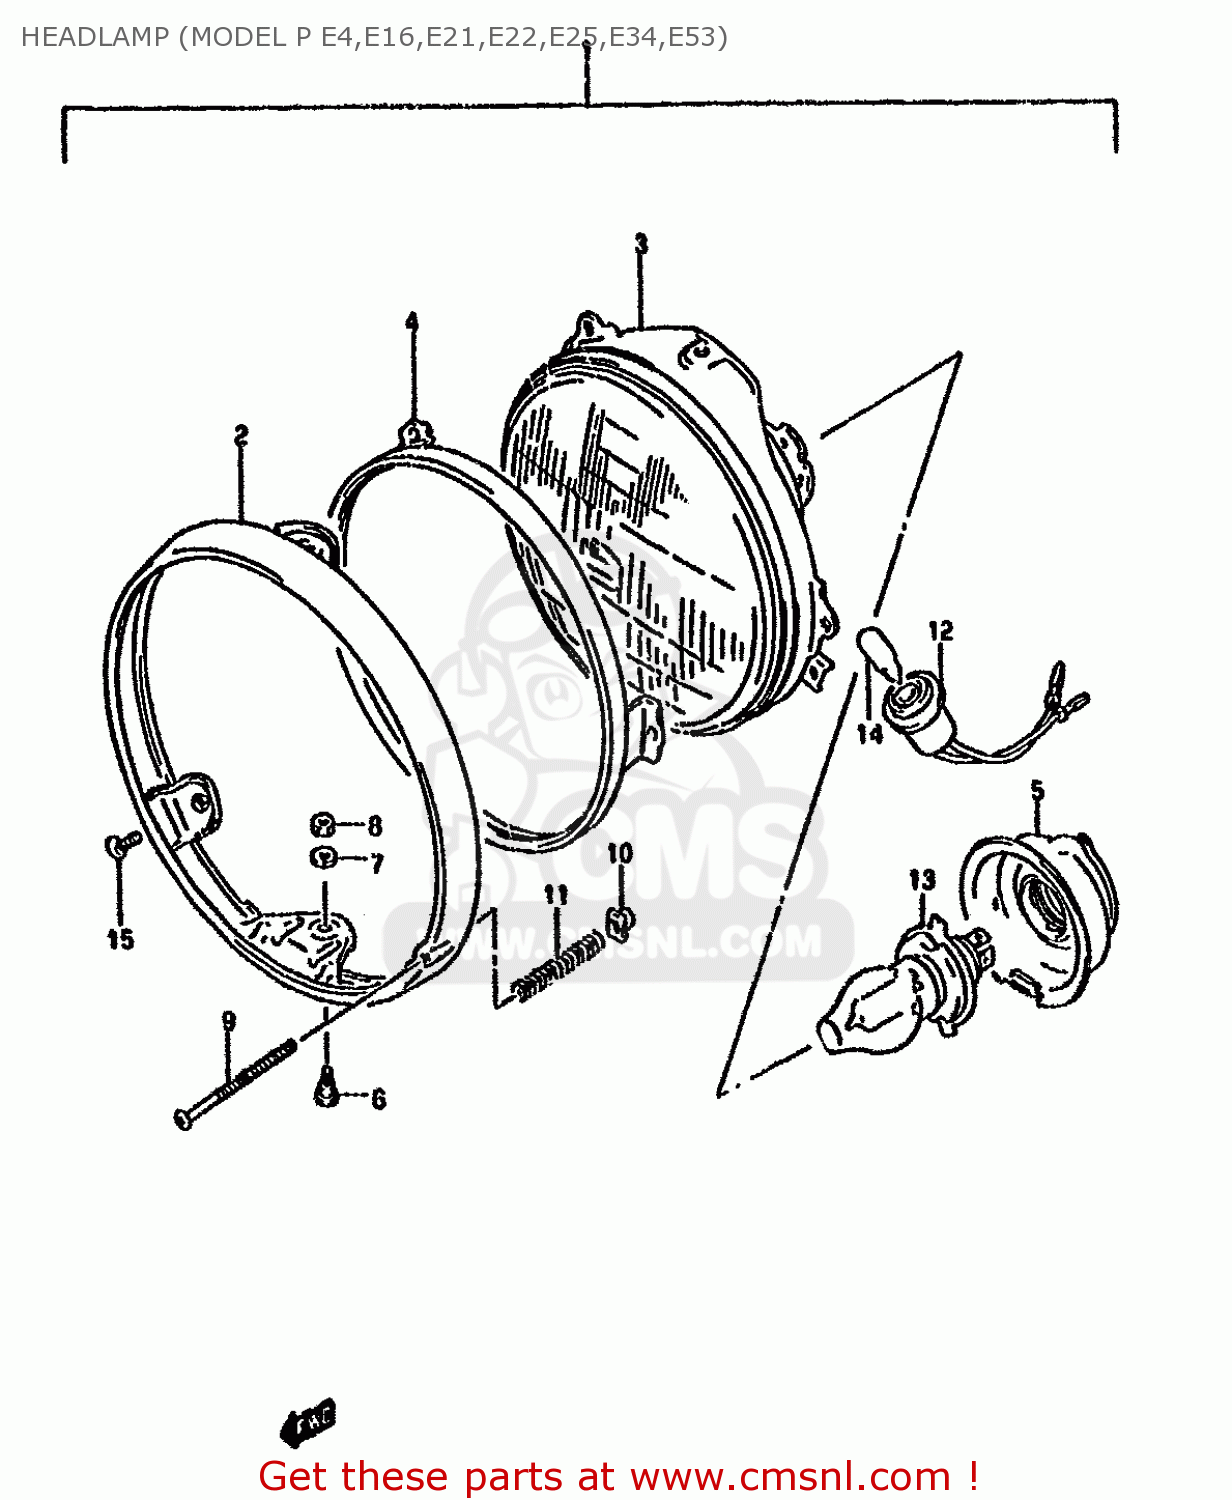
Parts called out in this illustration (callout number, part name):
1	HEADLAMP ASSY
2	RIM,HEADLAMP
3	LAMP UNIT
4	RETAINING RING
5	COVER,SOCKET
6	H/LAMP LENS UNIT FITING SCRE
7	LOCK WASHER
8	NUT 5MM
9	SCREW,HEADLAMP ADJUST
10	NUT
11	SPRING,ADJUSTING
12	SOCKET
13	BULB(12V60/55W,H4)
14	BULB(12V4W)
15	SCREW 5X12
16	REFLEX REFLECTOR,FR SIDE
17	BRACKET,FRONT SIDE REFLECTOR
18	NUT
20	BULB(12V60/55W,H4)
21	BULB(12V4W)
22	SCREW 5X12
